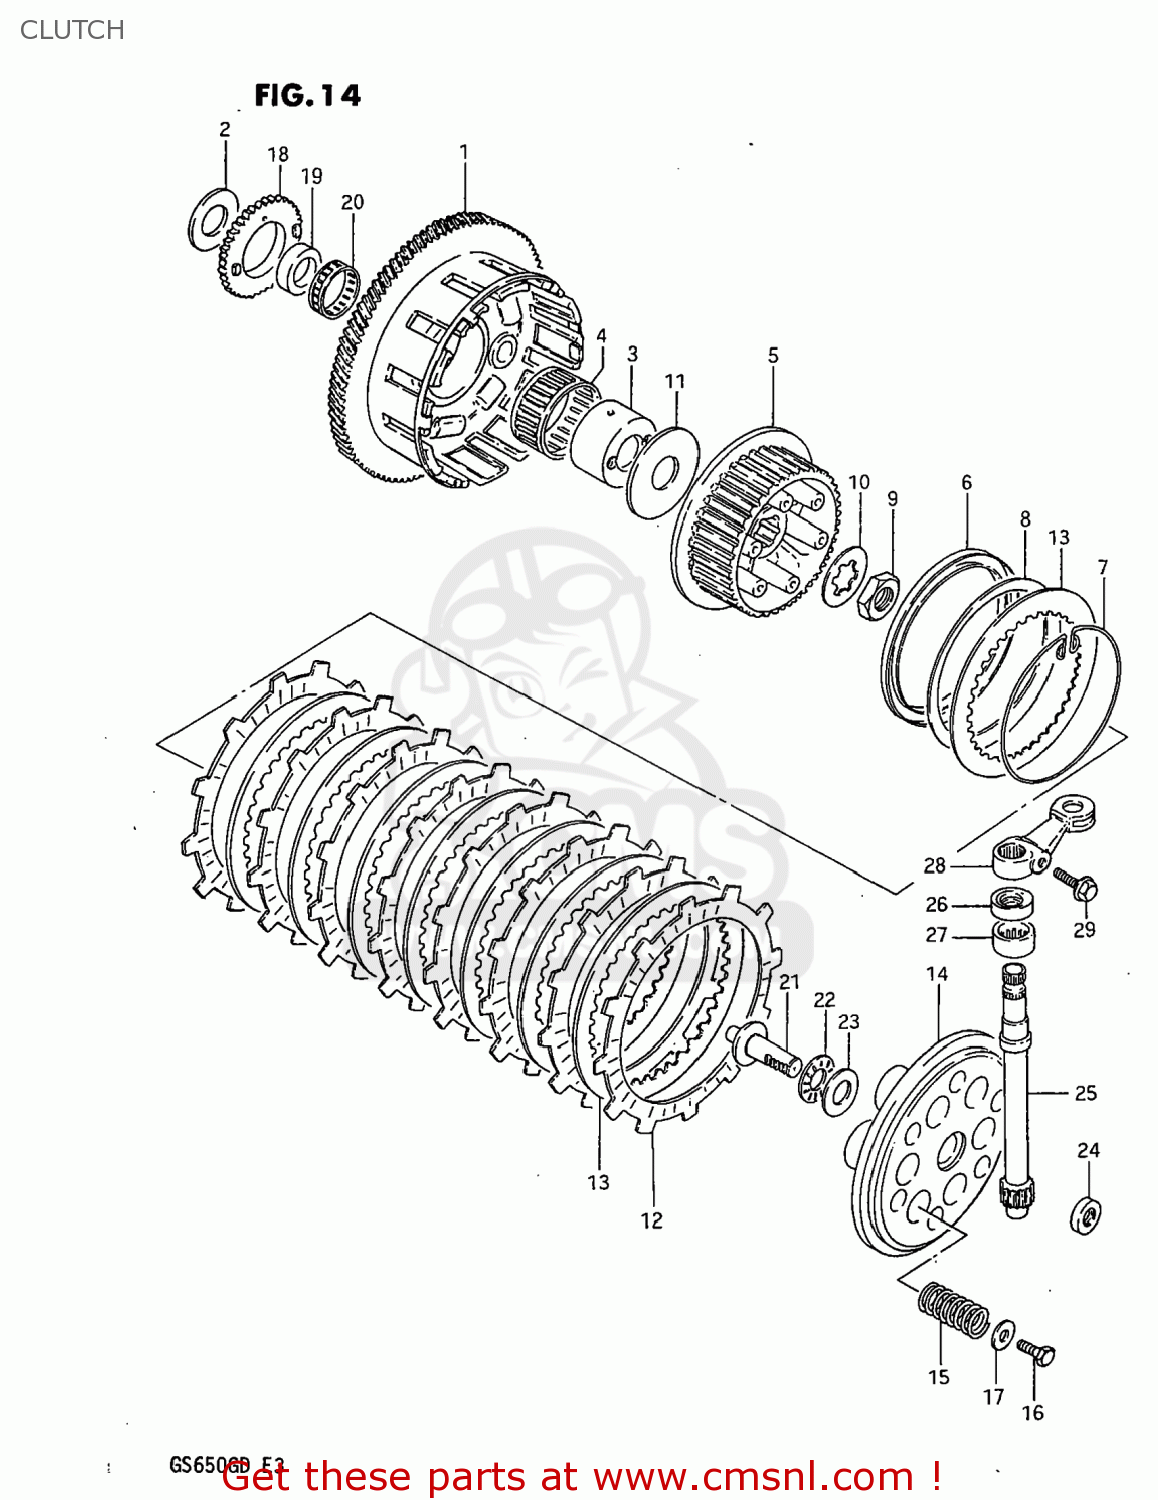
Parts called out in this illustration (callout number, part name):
1	GEAR ASSEMBLY,PRIMARY DRIVE
2	WASHER
3	SPACER
4	BEARING
5	HUB,CLUTCH SLEEVE
6	SEAT,WAVE WASHER
7	RING,STOPPER
8	WASHER
9	NUT
10	WASHER,LOCK
11	WASHER(25X66X3.5)
12	PLATE,CLUTCH DRIVE (MCA)
13	PLATE,CLUTCH DRIVEN(T:2.0) (NAS)
14	DISC,CLUTCH PRESSURE
15	SPRING
16	BOLT, UPPER
17	WASHER
18	GEAR,OIL PUMP DRIVE
19	SPACER,OIL PUMP DRIVE GEAR
20	BEARING(36X40X10)
21	RACK,CLUTCH RELEASE
22	BEARING(15X28X2)
23	WASHER
24	SEAL,OIL(10X16X5)
25	PINION,CLUTCH RELEASE
26	OIL SEAL
27	BEARING(15X22X12)
28	ARM,CLUTCH RELEASE
29	BOLT,REAR
